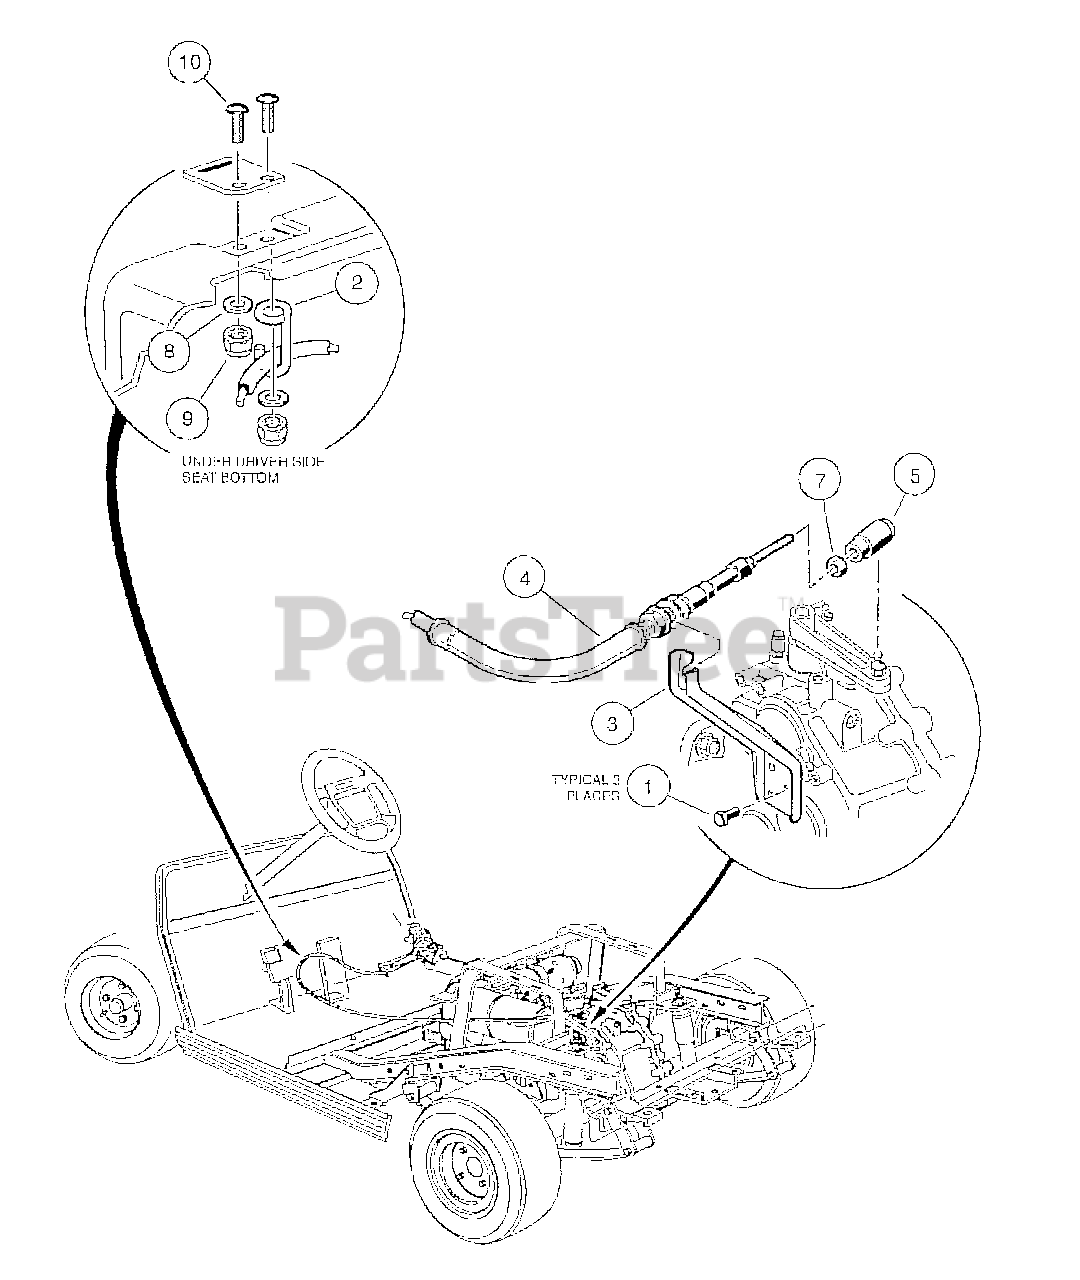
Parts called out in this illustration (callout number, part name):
1	Screw, 1/4 X 0.625 Hex-Head
2	Cable Retainer
3	Bracket, Shifter
4	FNR Shifter Cable
5	Joint, #10-32 Ball
6	Cable, Forward/Reverse Shifter
7	Nut, #10-32 Hex
8	Washer, 1/4 Type A Narrow Flat
9	Locknut, 1/4-20 Nylon Insert
10	Screw, 1/4-20 X 1.0 Truss-Head Machine
